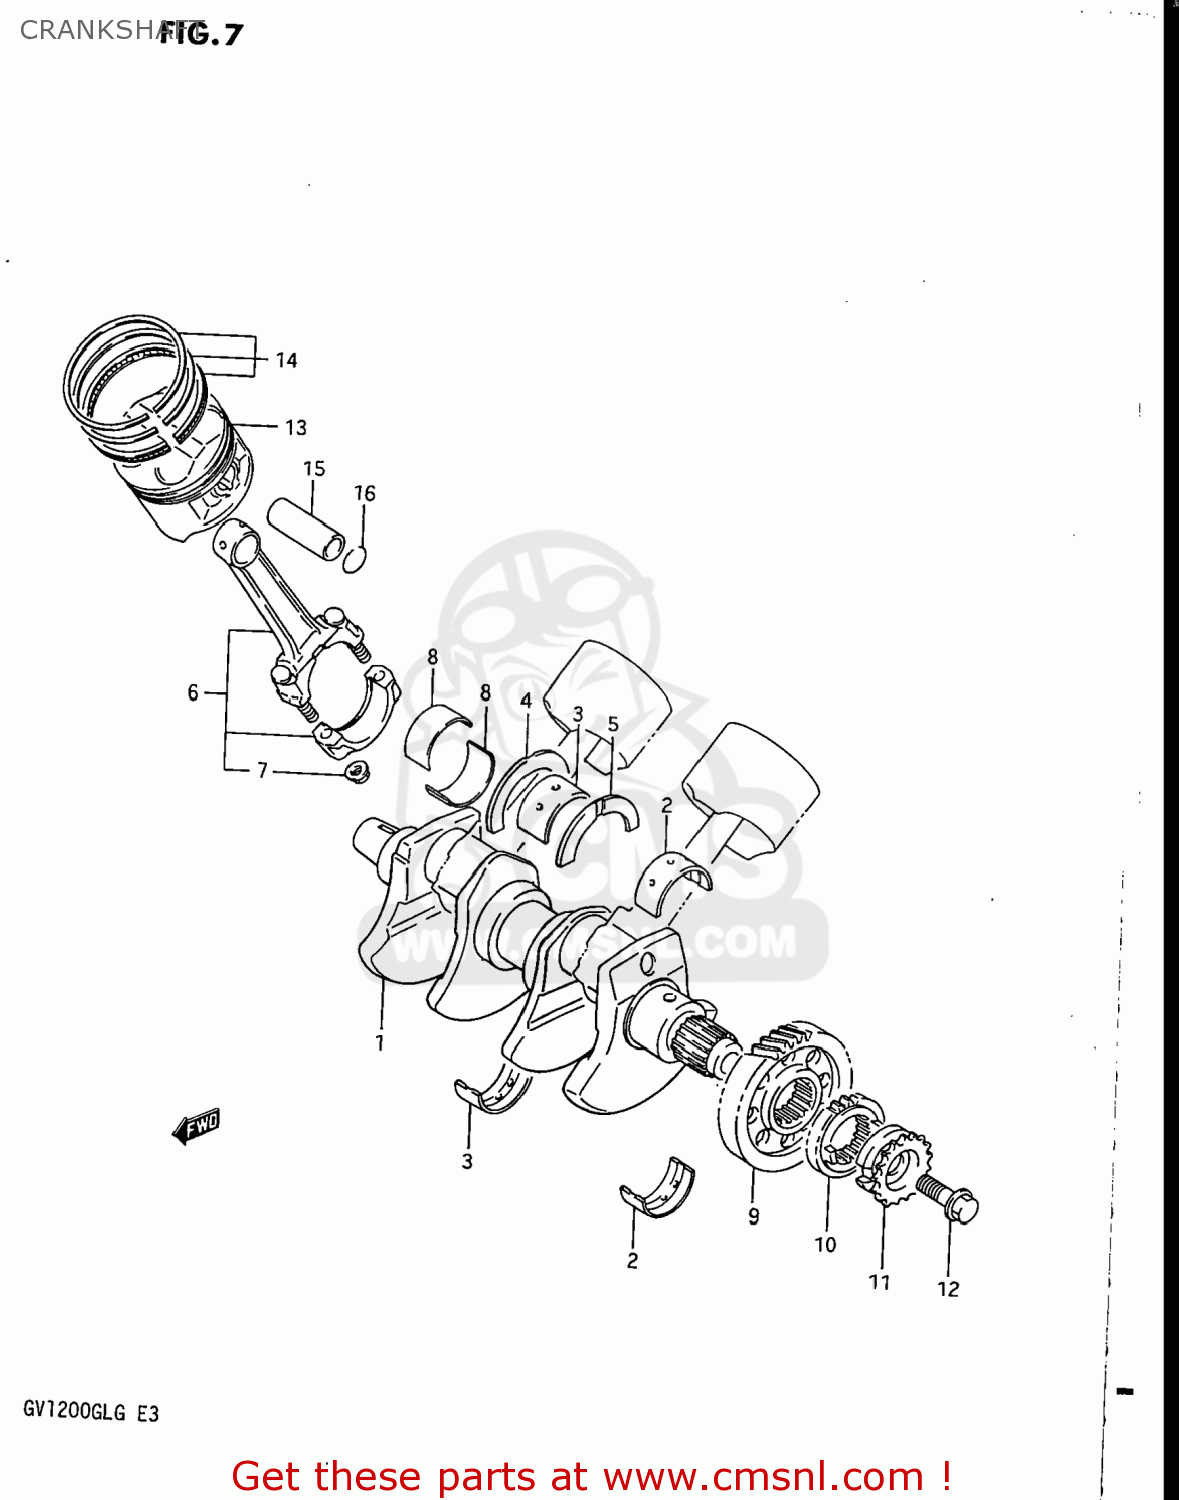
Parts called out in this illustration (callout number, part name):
1	CRANKSHAFT ASSEMBLY
2	METAL CRANKSHAFT
3	METAL CRANKSHAFT
4	PLATE,CRANK THRUST
5	PLATE,CRANK THRUST
6	CONNECTING ROD ASSEMBLY
7	NUT
8	BEARING,CRANK PIN
9	GEAR,PRIMARY DRIVE
10	SPROCKET,CHAIN DRIVE I
11	SPROCKET,WATER PUMP DRIVE
12	BOLT 12X30
13	PISTON (STD)
14	RING SET,PISTON
15	PIN,PISTON
16	CIRCLIP,PISTON PIN
